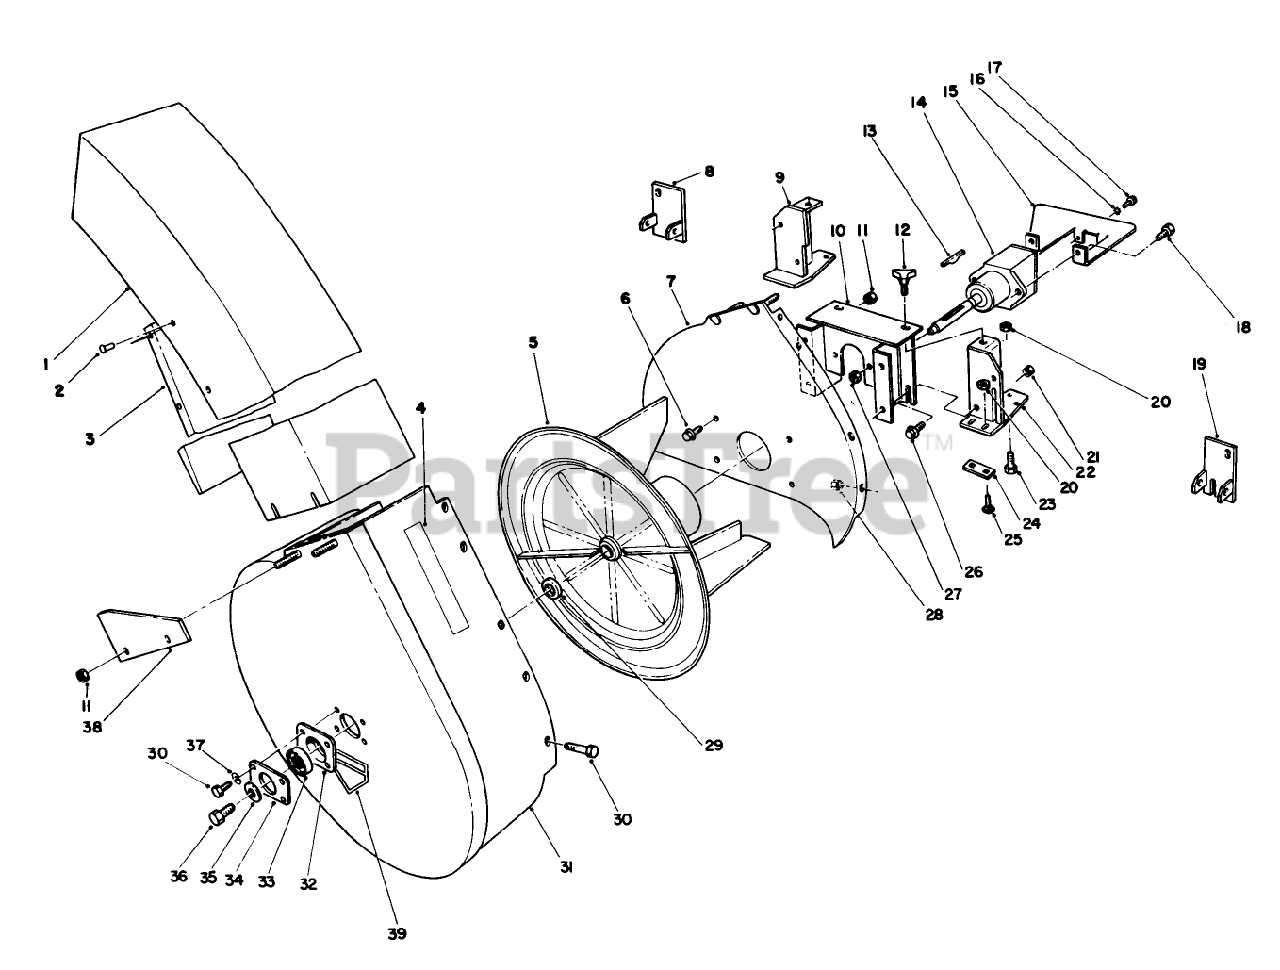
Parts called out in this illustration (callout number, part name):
1	CHUTE ASM
6	SCREW-HHF
9	LH BRACKET ASM, WELDED
11	NUT-LOCK, NI
16	WASHER-LOCK, EXT
18	SCREW-HH
20	NUT-LOCK, CONE
21	NUT-JAM
22	RH BRACKET ASM, WELDED
23	SCREW-HH
25	BOLT-CARR
26	SCREW-HHF
27	NUT-LOCK, NI
28	NUT-LOCK, NI
29	SPACER-BEARING
30	SCREW-HH
31	BLOWER HOUSING ASM
32	CUP-BEARING
33	BEARING-BALL
35	SPACER
36	SCREW-HH, LOCK
37	SCREW-HH
39	DECAL-DANGER
